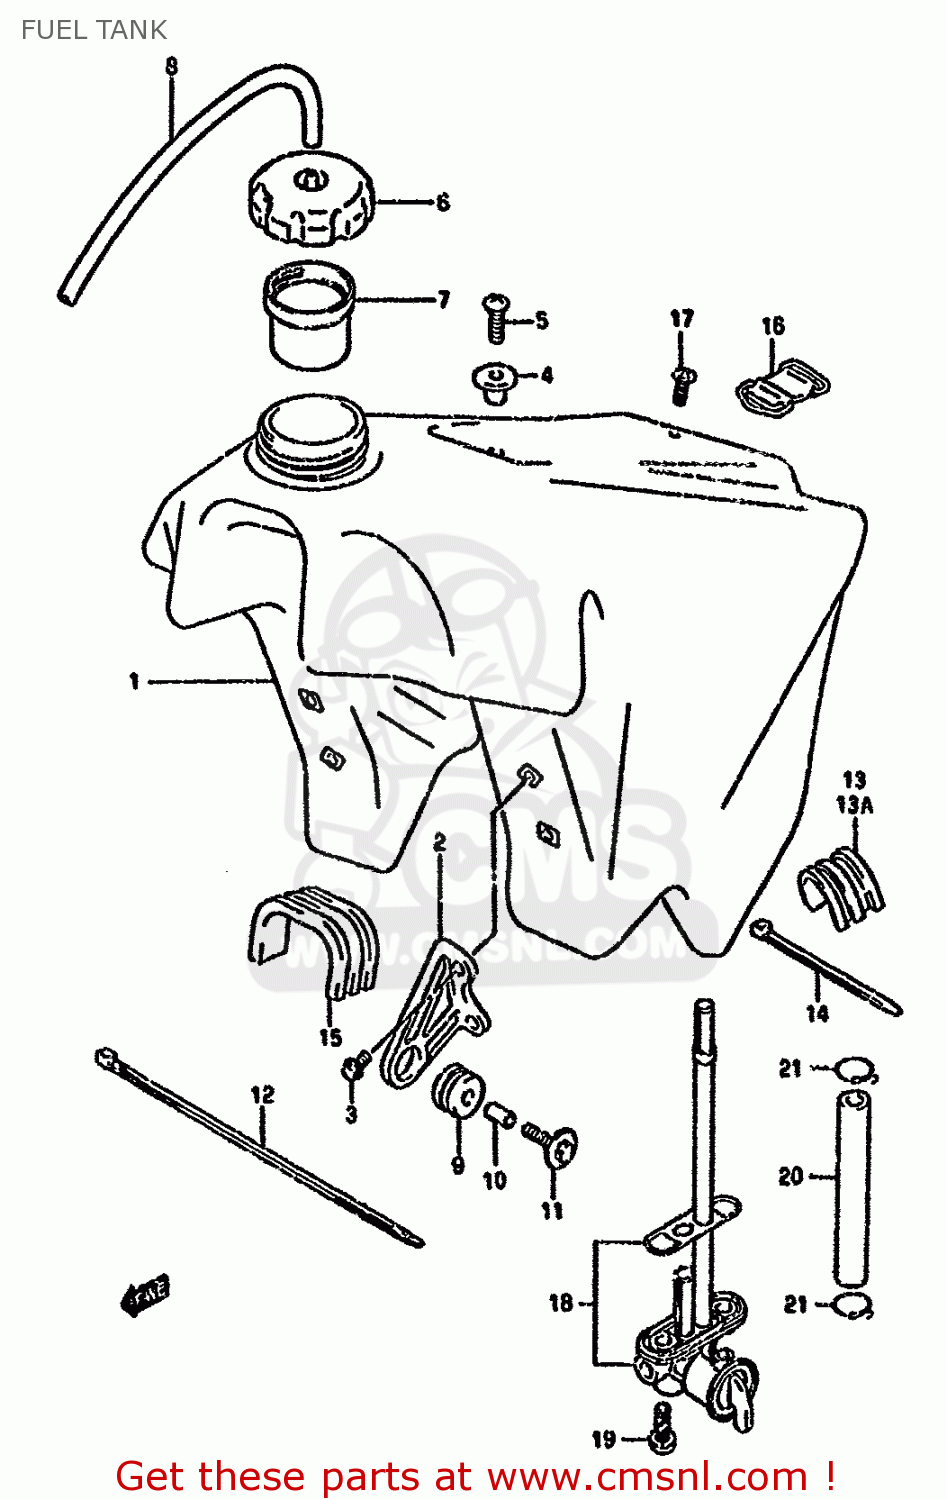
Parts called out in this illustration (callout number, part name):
1	TANK,FUEL (GRAY)
2	BRACKET,FUEL TANK FR
3	BOLT
4	HOOK,SEAT FR
5	SCREW
6	CAP ASSY,FUEL TANK
7	TUBE,FILLER INLET
8	HOSE
9	CUSHION,MUFFLER
10	SPACER (6.4X9X13.5)
11	BOLT(6X30)
12	CLAMP(L:300)
13	CUSHION,FUEL TANK NO.2
13A	CUSHION,FUEL TANK NO.2
14	CLAMP(L:145)
15	CUSHION,FUEL TANK
16	BAND,FUEL TANK RR
17	SCREW
18	COCK ASSY,FUEL
19	SCREW
20	HOSE (6.5X11.5X300)
21	CLIP
